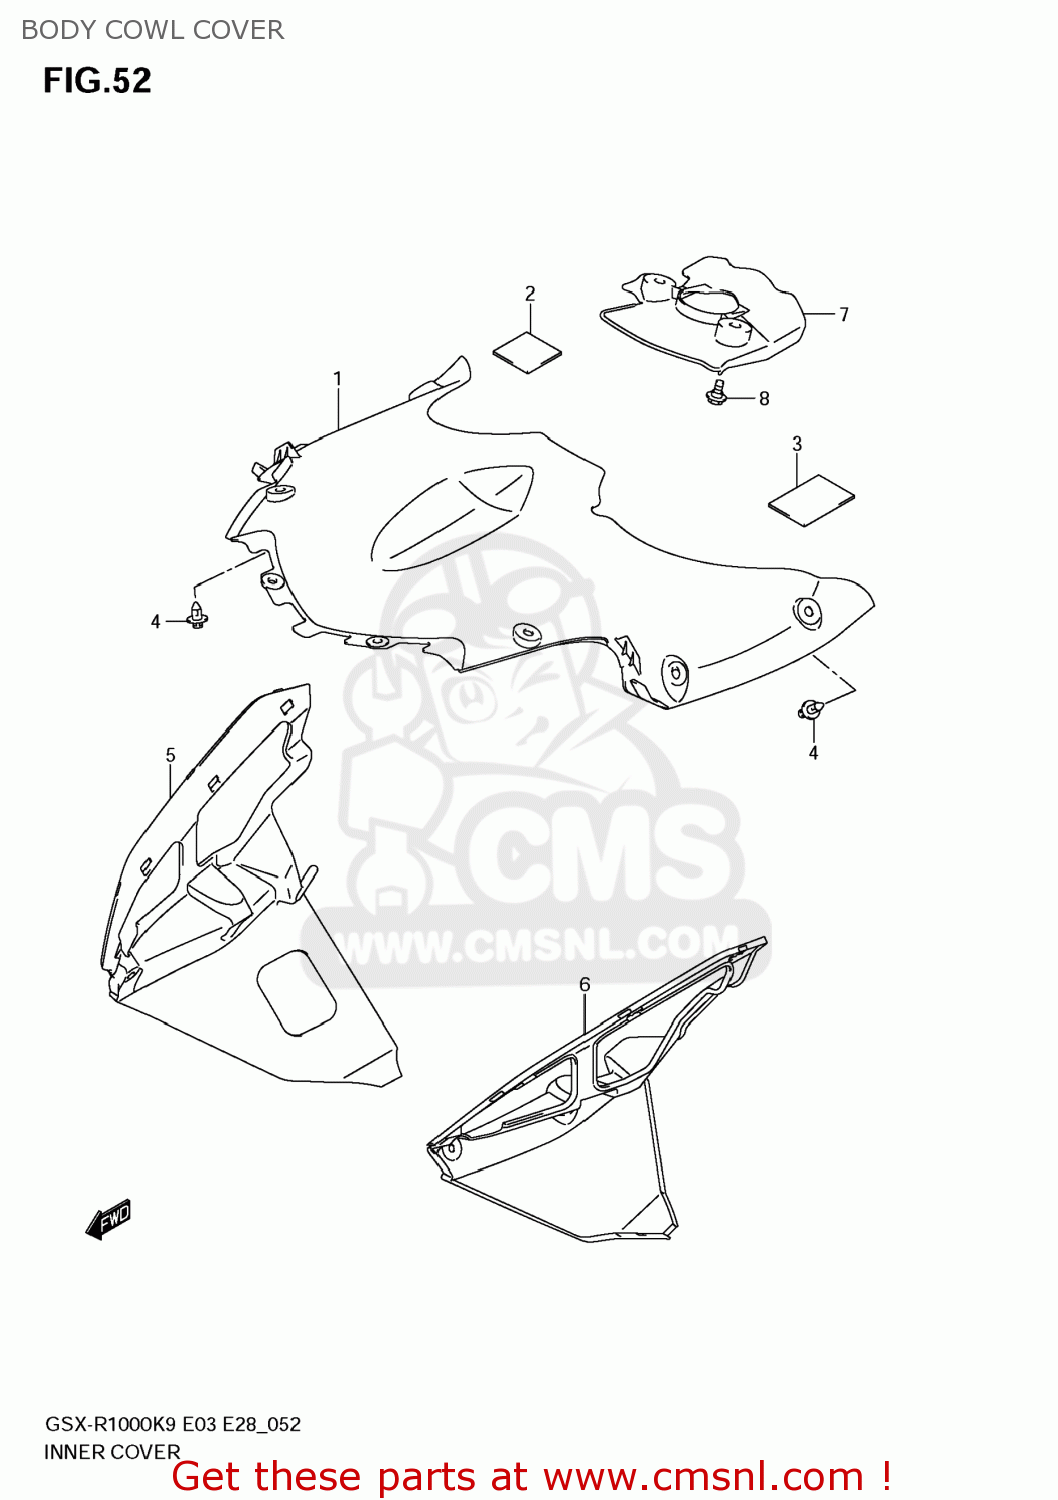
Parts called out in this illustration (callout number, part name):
1	COVER,BODY COWLING
2	PROTECTOR(30X80X1)
3	COVER,HARNESS
4	CLIP(BLACK)
5	COWLING,UNDER INNER,R
6	COWLING,UNDER INNER,L
7	COVER,LWR BRACKET
8	BOLT
